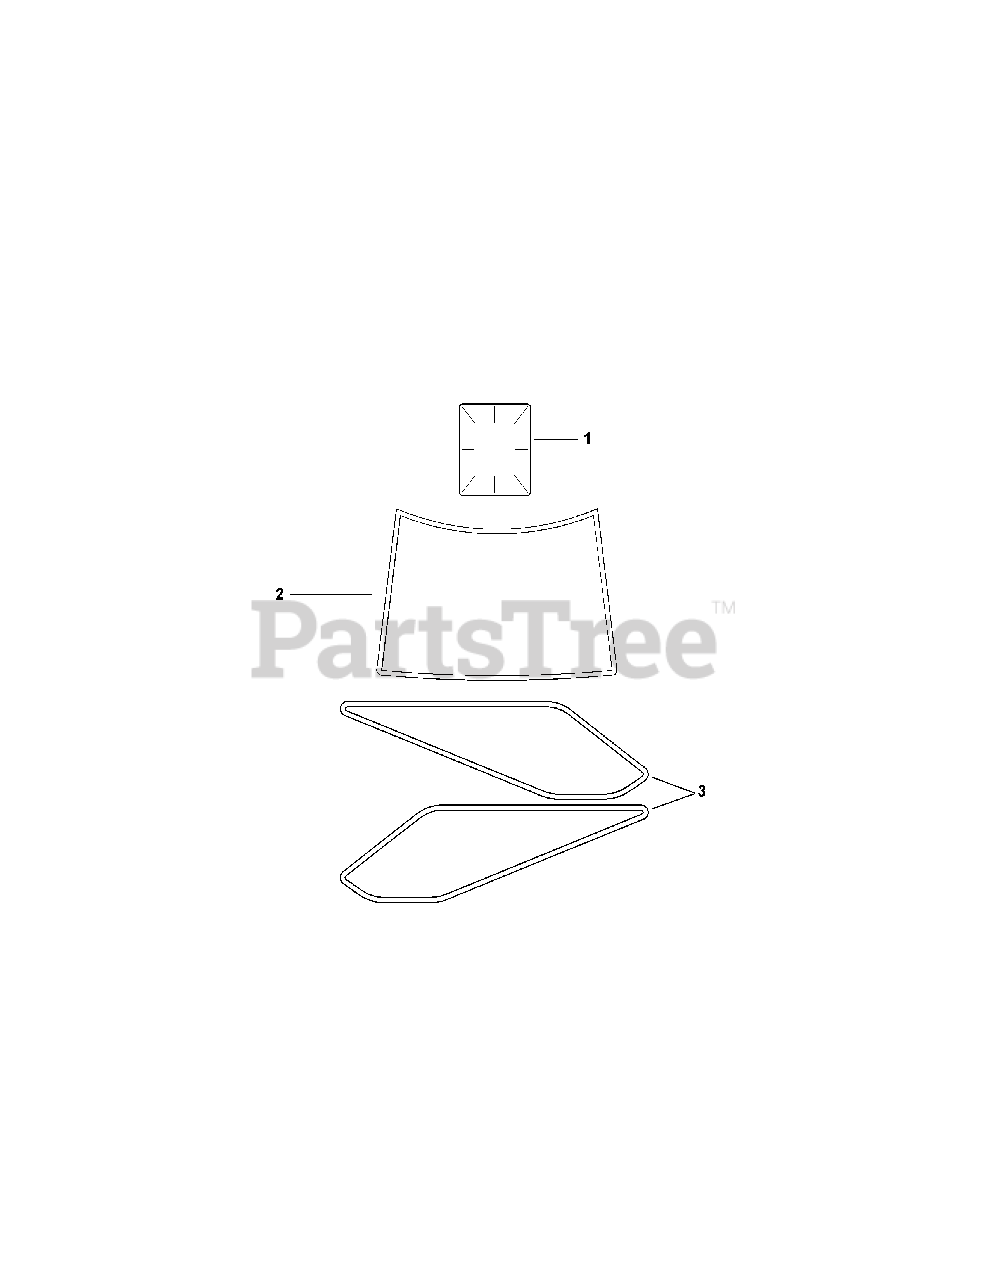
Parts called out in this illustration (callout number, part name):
1	Clear Laminate Decal
2	Decal, 24HP
3	Decal, Cub Twin Wings
